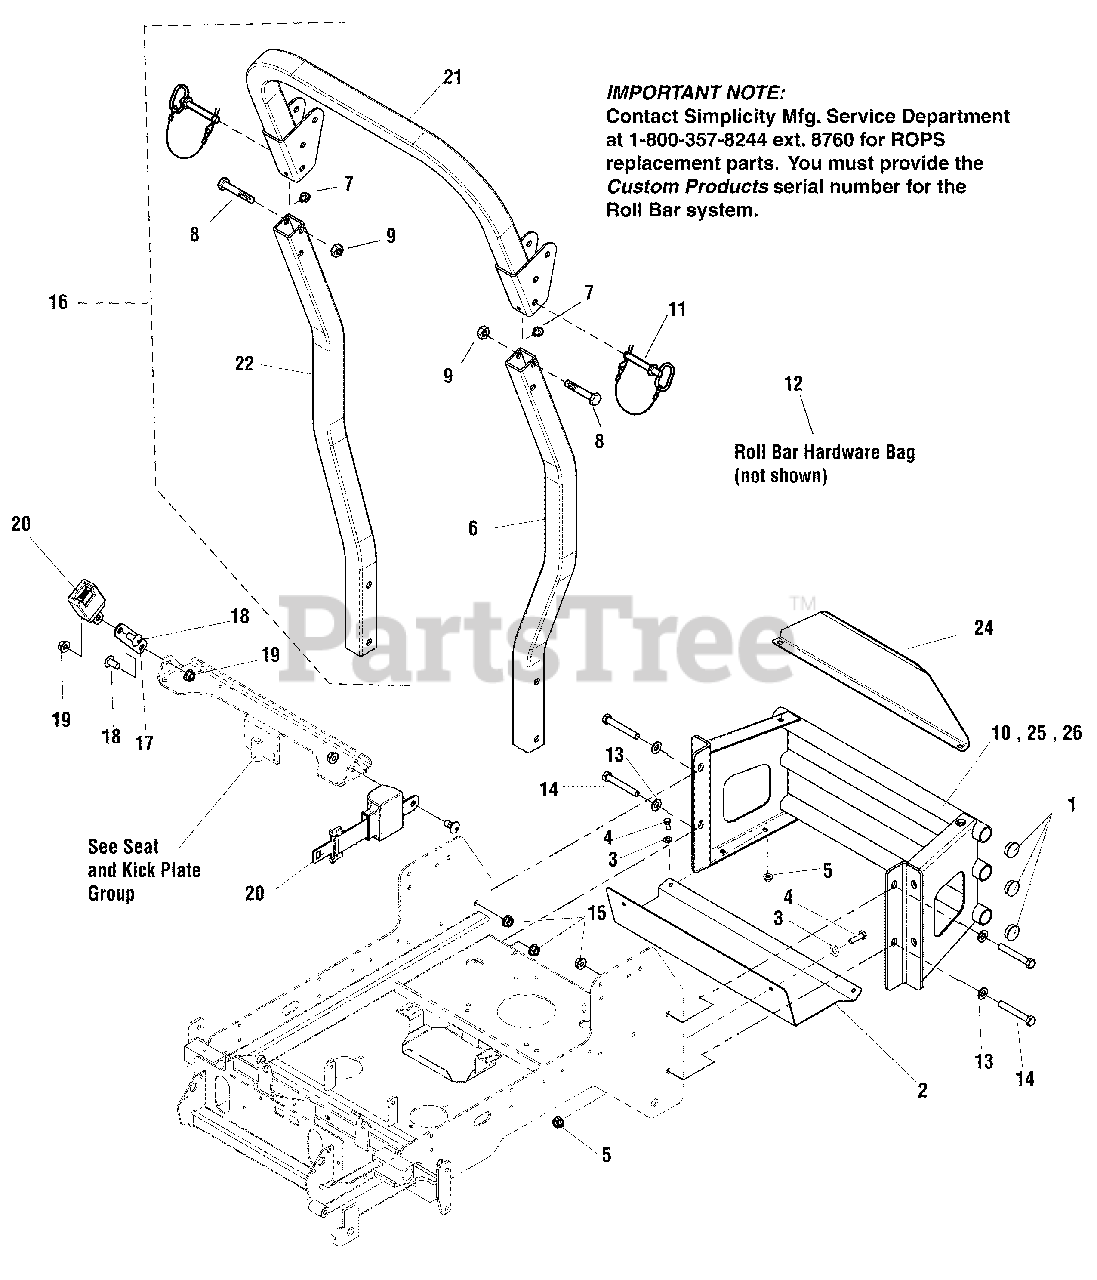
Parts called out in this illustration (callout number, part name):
1	PLUG, PANEL, 1.25 BLACK
2	PLATE, HEAT SHIELD - BLK
3	WASHER, 5/16 GD.9 FLAT
4	BOLT, 5/16-18 X 3/4" GRD5
5	NUT, 5/16-18 HEX NYLOCK FLANGE
6	ROLL BAR POST, LH
7	RUBBER BUMPER
8	BOLT
9	NUT
10	WELD, BUMPER - ORANGE
11	PIN, HITCH, BLACK W/ PLASTIC LANYARD
12	ROLL BAR HARDWARE BAG
13	WASHER, 1/2" SAE
14	BOLT, 1/2-13 X 3-1/4"
15	NUT, 1/2-13 HEX NYLOCK FLANGE
16	ROPS (Call 1-800-933-6175 x708 if replacing a ROPS)
17	EXTENSION, SEAT BELT
18	SCREW, 1/2 - 13 X 1.00 SCHS
19	NUT, 1/2-13 HEX NYLOCK FLANGE
20	SEAT BELT, RETACTING - ASSM
21	ROLL BAR TOP LOOP
22	ROLL BAR POST, RH
24	PLATE, CARB PROTECTOR
25	WELD, BUMPER - ORANGE
26	WELD, BUMPER - ORANGE
